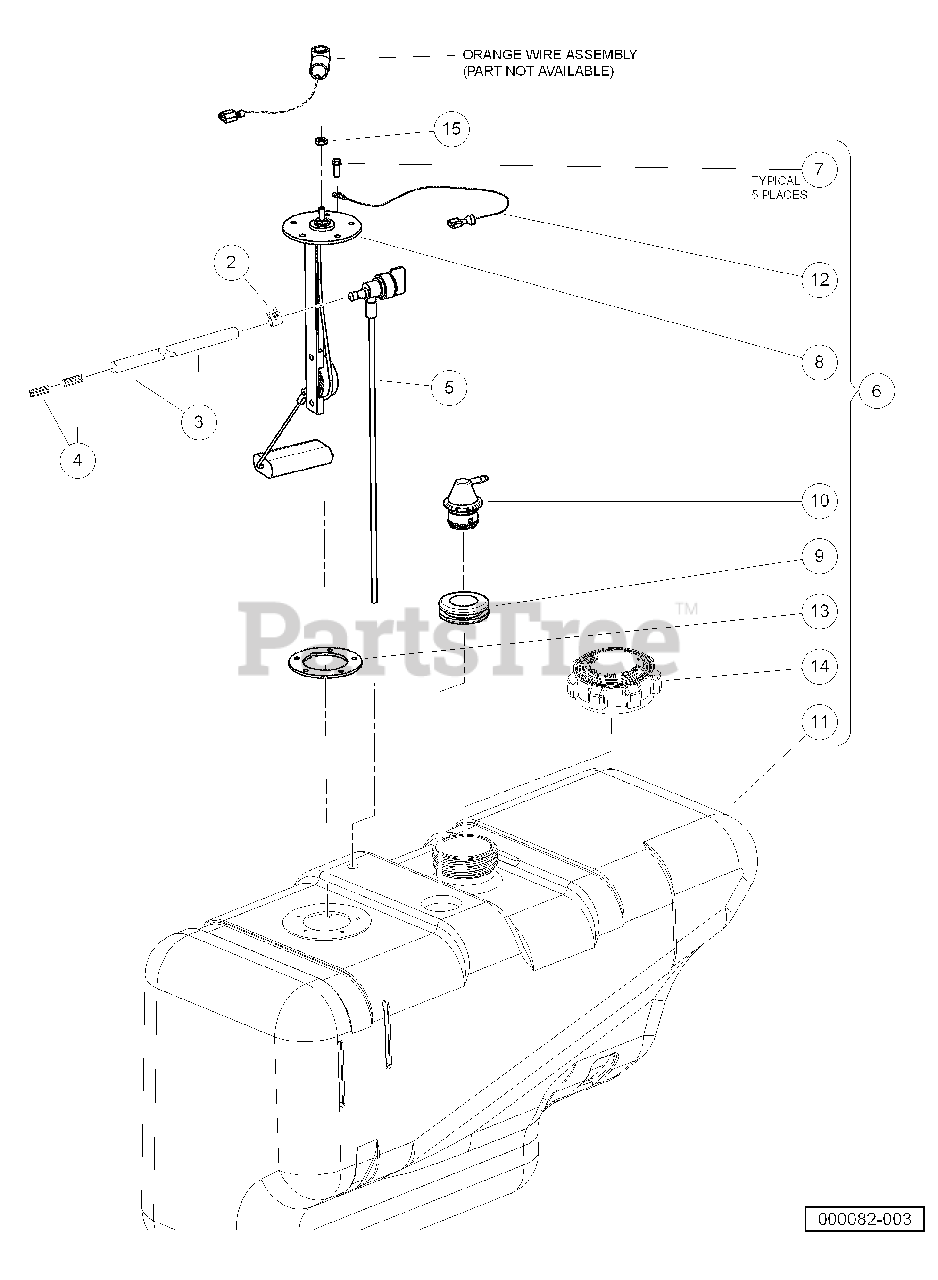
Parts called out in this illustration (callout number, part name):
1	Tank Kit w/Sending Unit
2	Clamp, 0.301 ID Hose
3	Fuel Line
5	Fuel Pickup w/Shut-Off Valve
6	Fuel Tank with Sending Unit
7	Screw, #10-16 Hex-Head Hi-Lo
8	Sending Unit, Fuel Level
9	Insulation Grommet
10	Vent, Fuel Tank
11	Fuel Tank with Vent and Sending Unit Hole
12	Wire Assembly #16 Black
13	Gasket, Rubber
14	Cap, Fuel Tank, Gasoline
15	Nut, #10-32 Brass Hex
